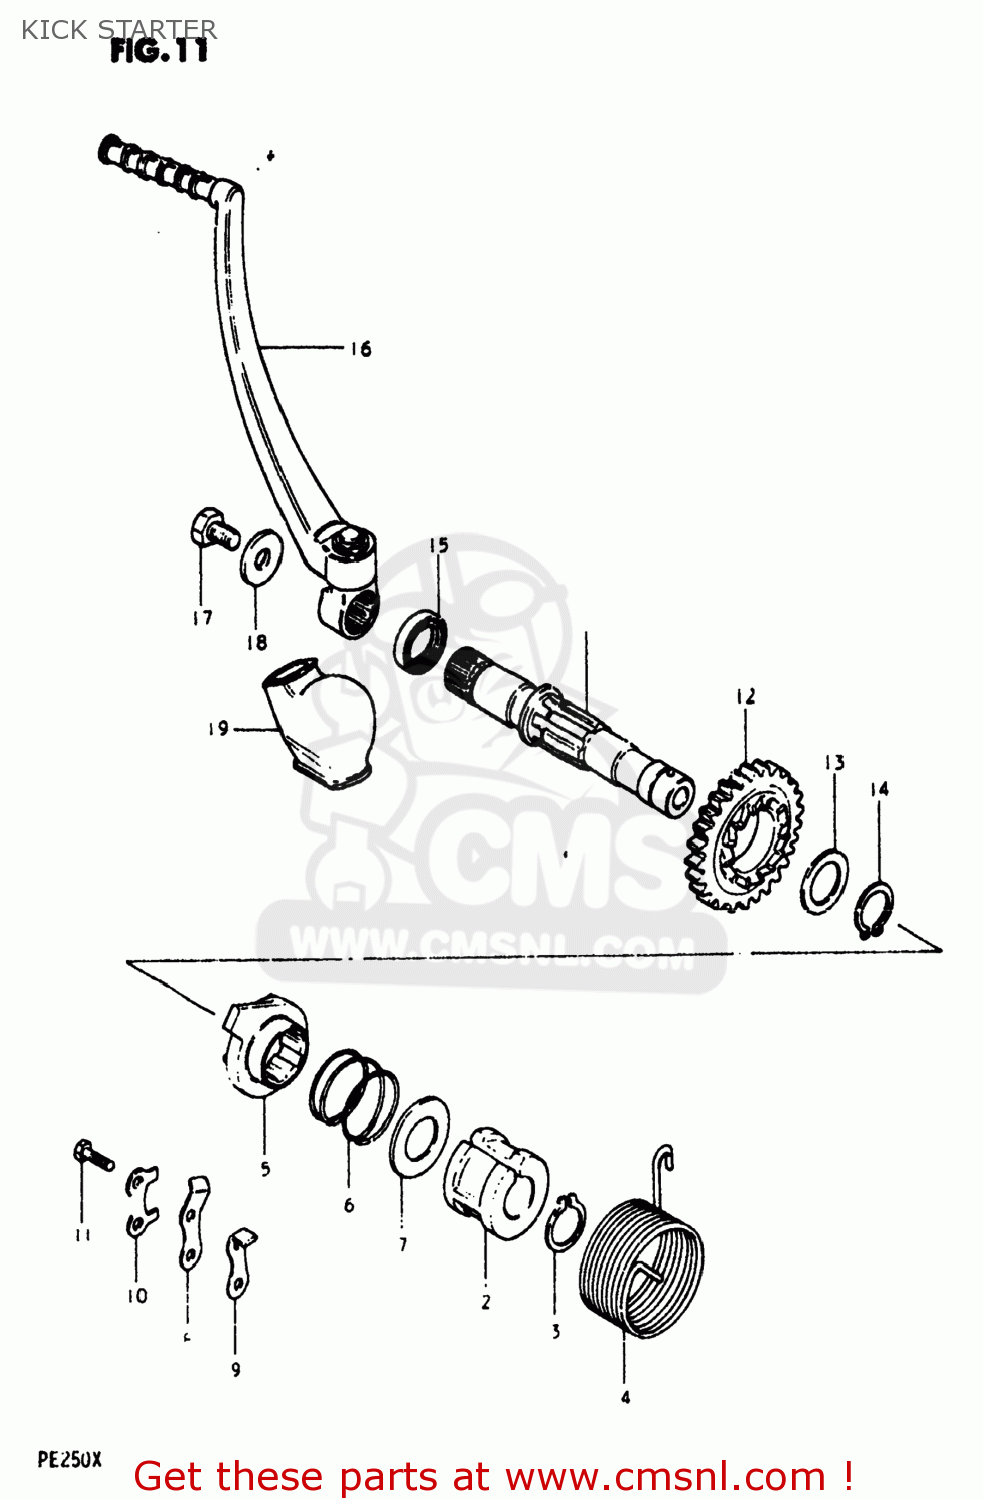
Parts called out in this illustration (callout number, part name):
1	SHAFT,KICK STARTER
2	GUIDE,KICK STARTER SFT SPRING
3	CIRCLIP
4	SPRING
5	STARTER,KICK
6	SPRING
7	WASHER
8	GUIDE,KICK STARTER
9	STOPPER,KICK STARTER
10	WASHER
11	BOLT
12	GEAR,KICK STARTER DRIVE
13	SHIM
14	CIRCLIP
15	SEAL,OIL(20X27X5)
16	LEVER ASSEMBLY,KICK STARTER
17	BOLT
18	WASHER(8.2X23X3.2)
19	COVER,KICK LEVER JOINT
